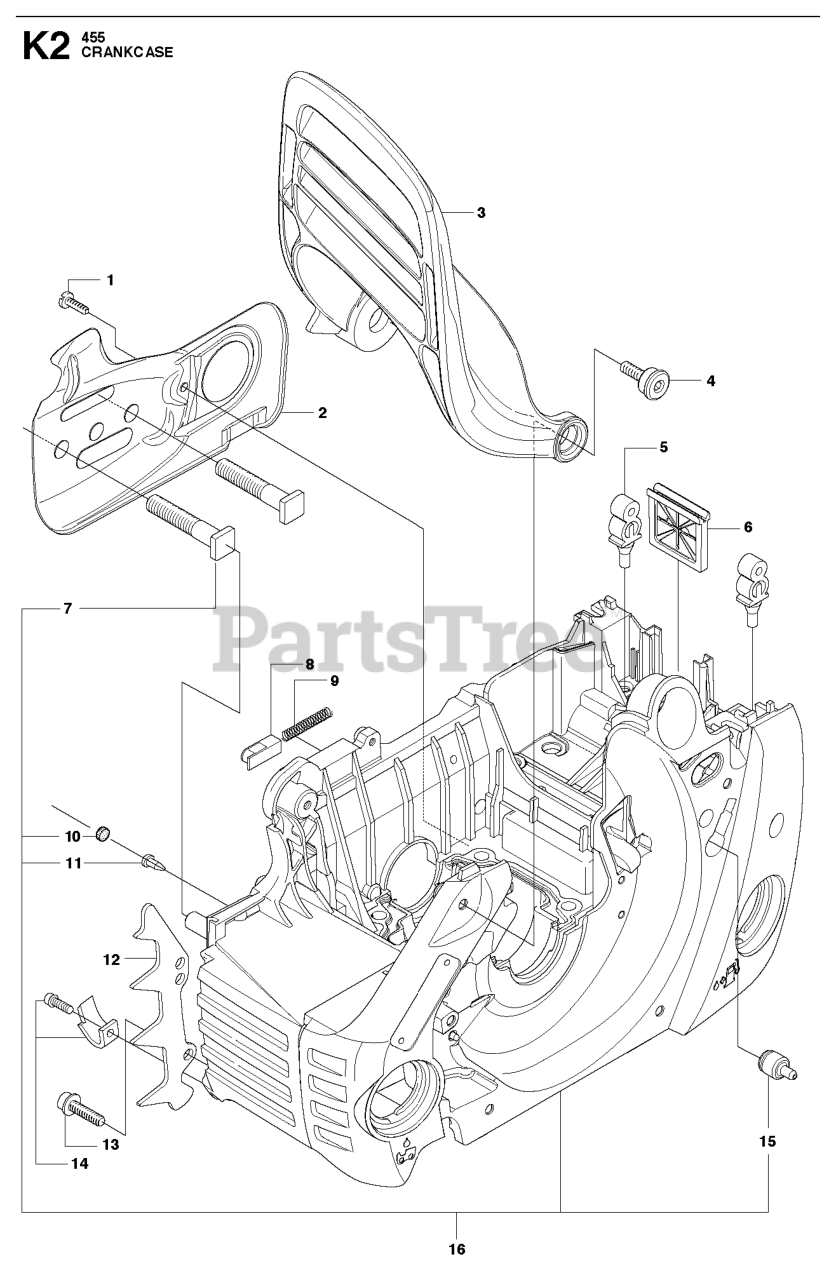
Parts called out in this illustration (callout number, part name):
3	HAND GUARD
4	SCREW, HAND GUARD
9	LOCK SPRING
10	PLUG
11	VALVE-CHECK (DUCKBILL)
12	FELLING DOG
13	SCREW IHSCFT
14	CHAIN CATCHER
15	FUEL TANK VENT
16	CRANKCASE
